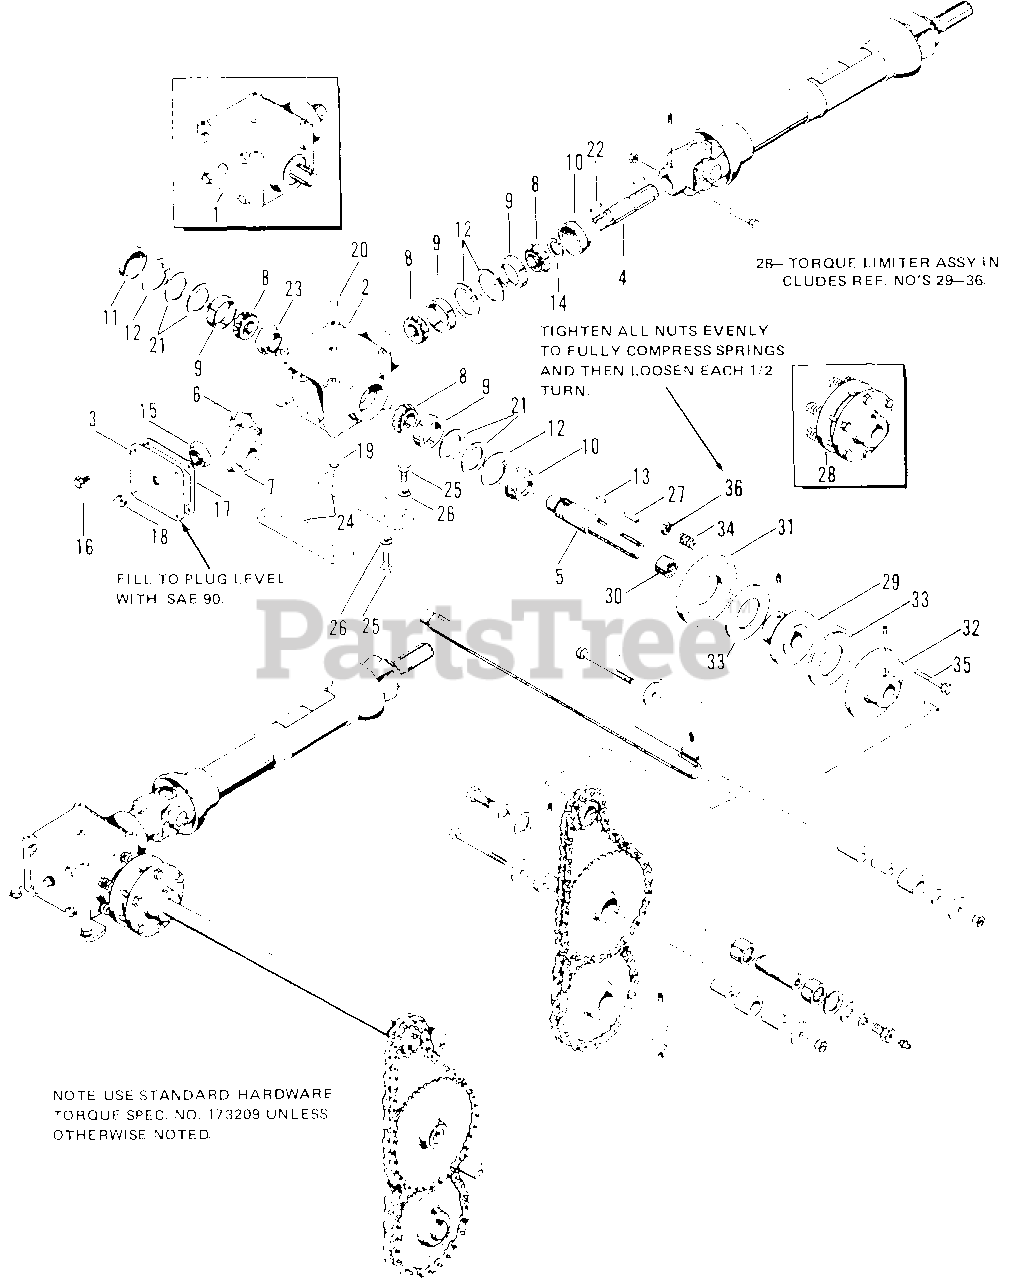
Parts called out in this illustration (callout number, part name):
1	BOX, Gear
4	SHAFT, Input
5	SHAFT, Output
6	GEAR, 16 T
7	GEAR, 24 T
8	CONE, Bearing
9	CUP, Bearing
12	RING, Retaining, 2" Internal
13	KEY, Woodruff, 1/4 x 7/8
14	RING, Retaining
15	NUT, Stake
16	CAPSCREW, Hex Hd., 5/16-18 x 3/4
18	PIPE, Plug, Sq. Hd., Solid, 1/8
19	PIPE, Plug, Cntrsk, Sq. Hd., 3/8
20	PLUG, Vent
23	NUT, Stake
25	CAPSCREW, Hex Hd., 3/8-16 x 1
26	LOCKWASHER, Spring, 3/8
28	LIMITER ASSY, Torque, (Includes Ref. No's 29-36)
29	HUB ASSY, Clutch
31	PLATE, Clutch
32	FLANGE, Clutch
33	DISK, Clutch
35	CAPSCREW, Hex Hd., 5/16-18 x 2-1/2
36	NUT, Hex, Lock, 5/16-18
